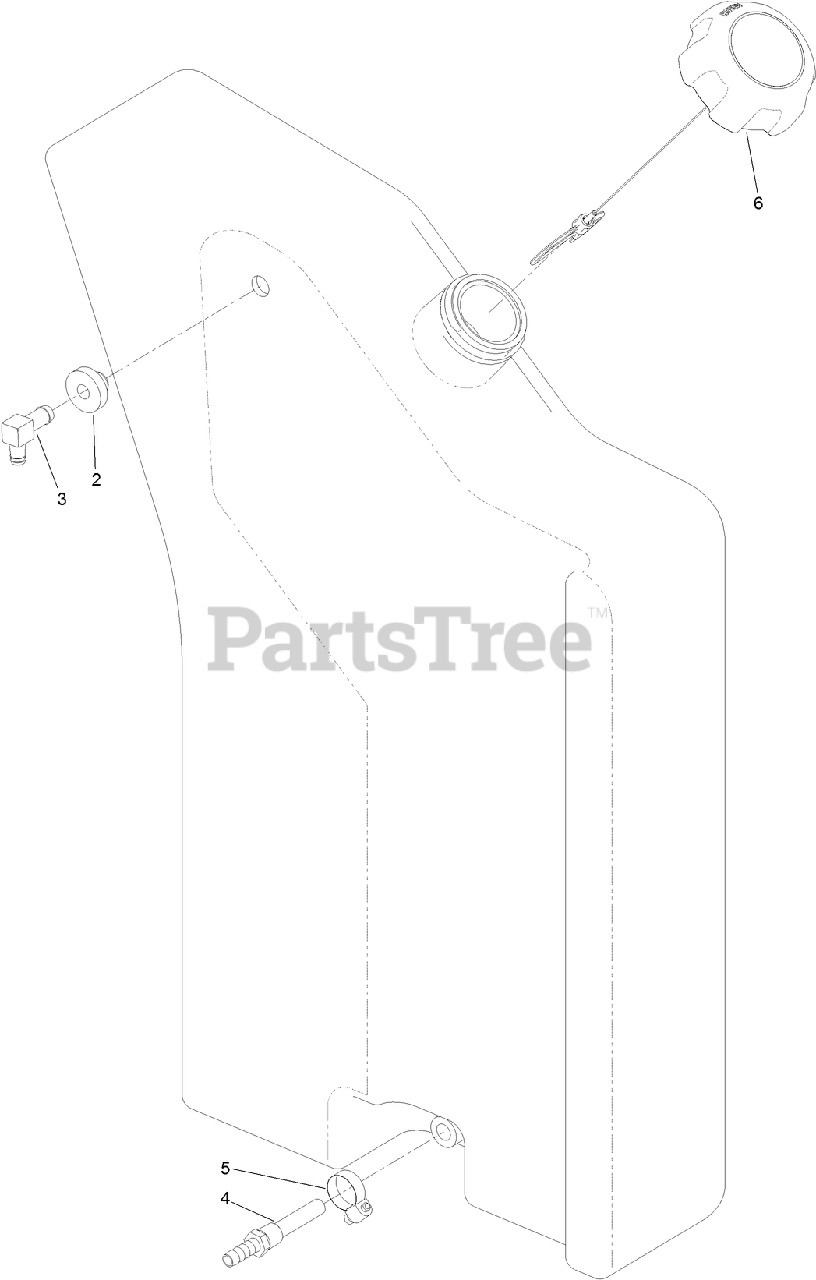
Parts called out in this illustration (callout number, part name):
2	BUSHING
4	FITTING-STRAINER
5	CLAMP-HOSE
6	CAP-DIESEL,
